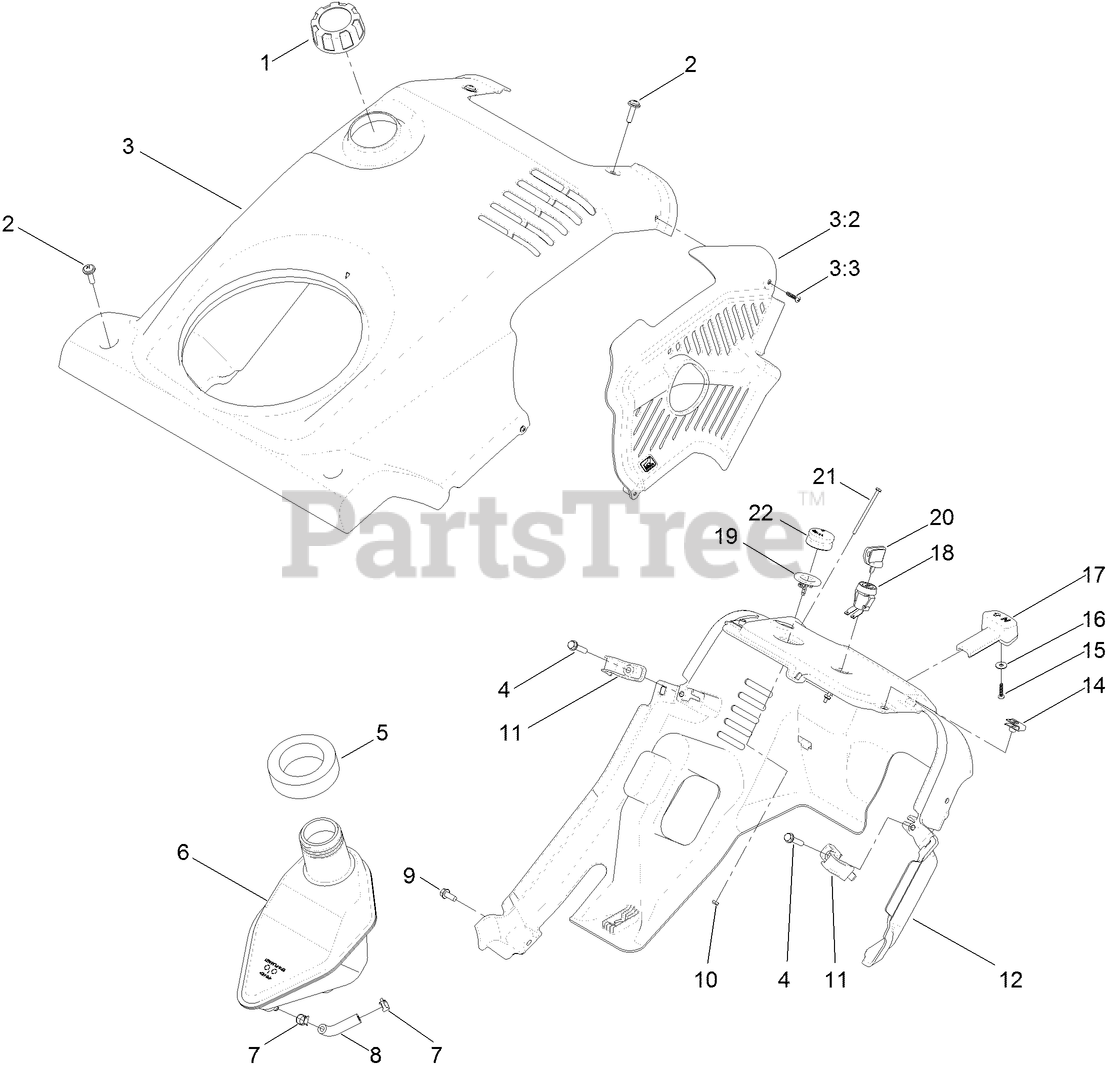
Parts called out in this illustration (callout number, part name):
1	FUEL CAP ASM
2	SCREW-PPH
3	SHROUD ASM
3:2	BAFFLE-EXHAUST
3:3	SCREW-PPH
4	SCREW-PLASTITE
5	SEAL-TANK
6	TANK-FUEL, GAS
7	CLAMP-HOSE
8	HOSE-FUEL
9	SCREW-HWH
10	NUT-HEX
11	CLIP-SHROUD
12	SHROUD-LOWER
15	SCREW-PPH
16	WASHER-PLAIN
17	KNOB-CHOKE
18	SWITCH
19	BODY-PRIMER
20	KEY-IGNITION
21	SCREW-HWH
22	BULB-PRIMER
